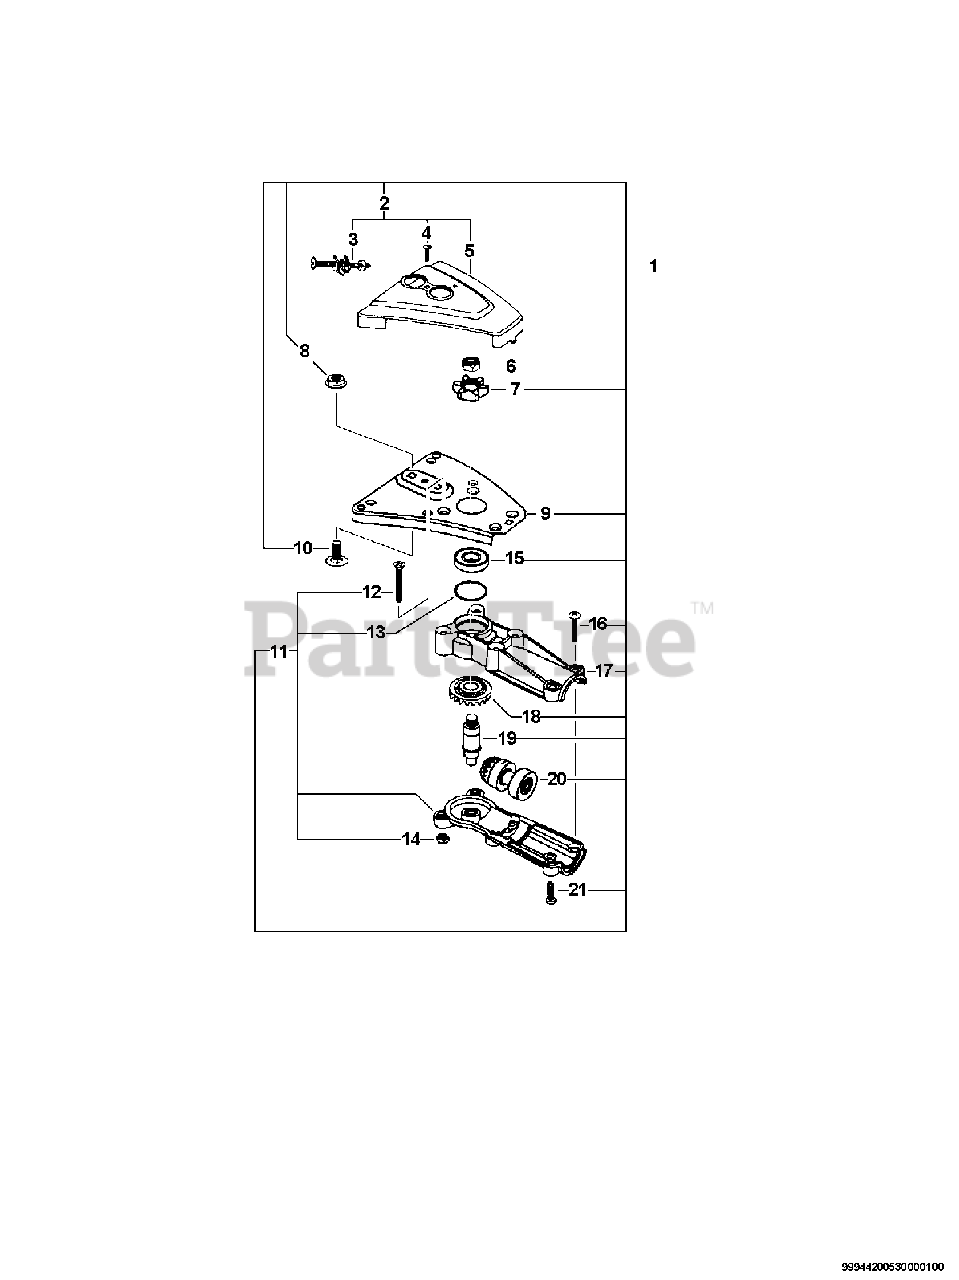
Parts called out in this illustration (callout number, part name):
1	CUTTING HEAD ASSY
2	SPROCKET COVER ASSY
3	TENSIONER, CHAIN
4	SCREW - 8-32 X 1"
5	GUARD, SPROCKET
6	NUT
7	SPROCKET
8	NUT - FLANGE
9	SAW BAR CARRIER
10	BOLT
11	CASE, GEAR - RIGHT
12	SCREW
13	SHIM .004"
14	LOCKNUT - 10-24
15	BEARING, BALL - 6001 DDU
16	SCREW - 10-24 X 1-1/4"
17	CASE, GEAR - RIGHT
18	GEAR - BEVEL
19	SHAFT GEAR ASSY
20	SHAFT GEAR ASSY
21	SCREW
